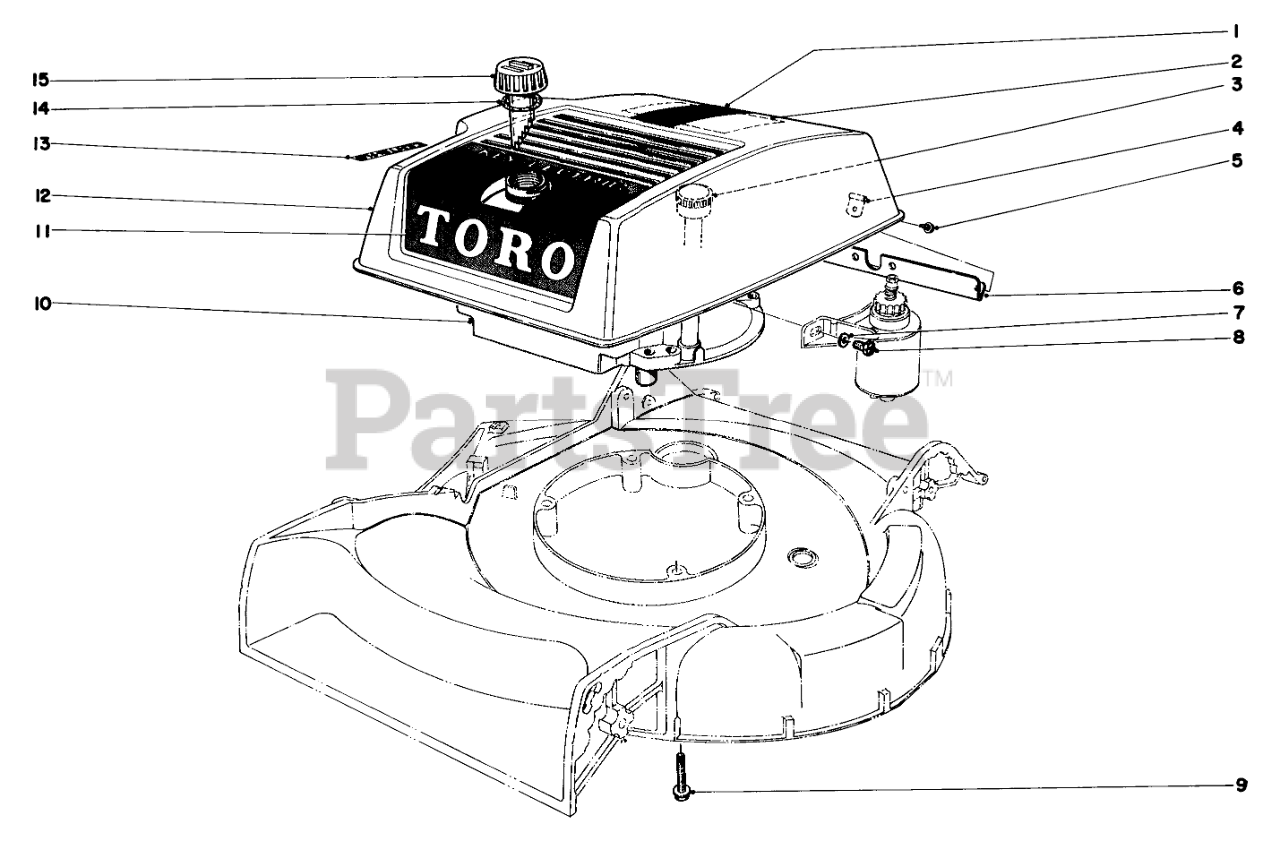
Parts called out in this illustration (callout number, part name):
1	Decal
2	Decal-Maintenance
3	Dip Stick
4	Hinge
5	SCREW-HWHTF
6	Shroud Bracket
7	WASHER-FLAT
8	Screw
9	3/8-16 X 2-3/4 CAPSCR
10	Engine
11	Decal
12	Shroud
13	Decal, Air Cleaner
14	Gasket
15	Gas Cap
